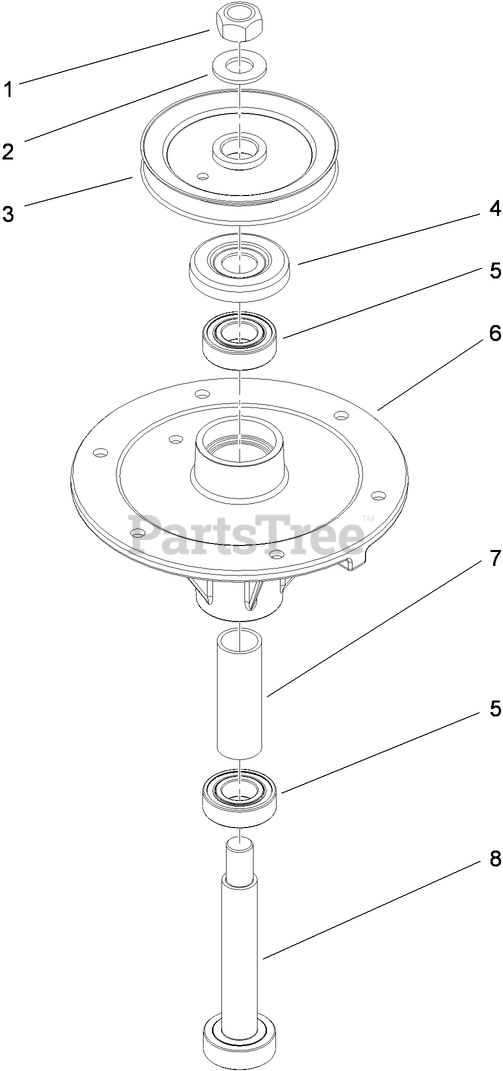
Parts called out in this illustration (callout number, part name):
1	NUT-HEX
2	WASHER
3	PULLEY ASM
4	SHIELD-BEARING
5	BEARING-BALL
6	HOUSING-SPINDLE
7	SPACER-BEARING
8	SHAFT-SPINDLE
